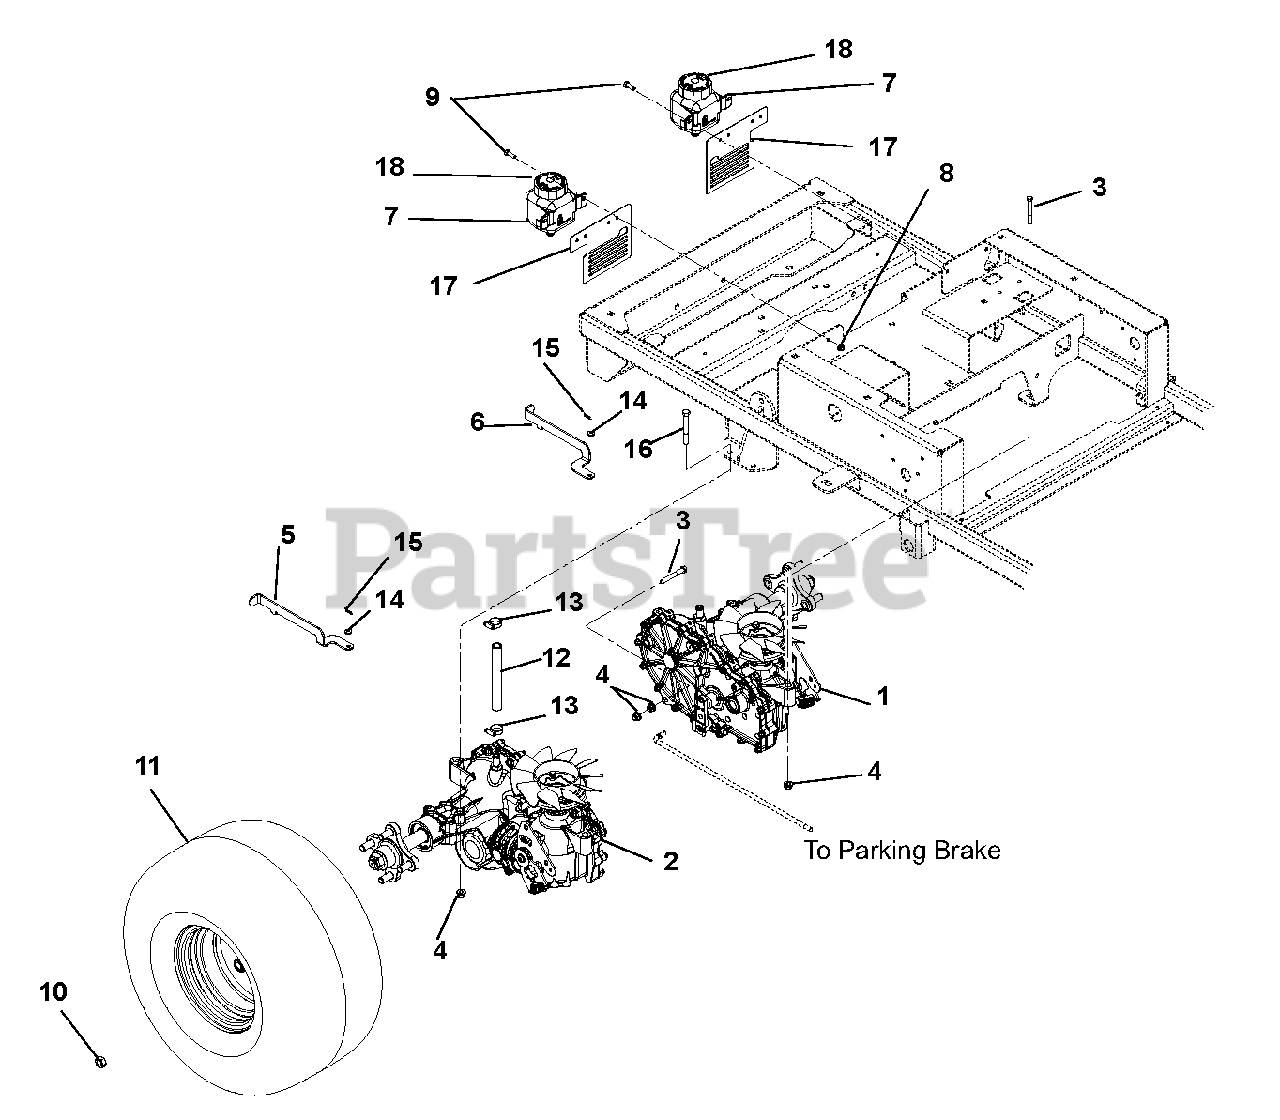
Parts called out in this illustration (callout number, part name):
1	Transaxle, ZT2800 Left Hand
2	Transaxle, ZT2800 Right Hand
3	Bolt, Hex .31-18 x 2.25 Grade 5
4	Nut 5/16-18 Flange Nyloc
5	Dump Valve, Right Hand
6	Dump Valve, Left Hand
7	Tank, Expansion ZT2800
8	Nut, Locking Top Flange .25-20
9	Bolt, Hex .25-20 x .75 Grade 5
10	Nut, Wheel .50-20 13/16
11	Tire/Wheel Assembly, 20 x 8.0-8
12	Hose, Oil Reservior
13	Clamp, .88 Diameter Hose
14	Washer, Flat Steel .265 x .50 x .087
15	Pin, Hair Internal .06 x .18 x .77
16	Bolt, Hex .31-18 x 2.75
17	Bracket, Rear Fan Guard
18	Cap, Hydro Reservoir Replacement
